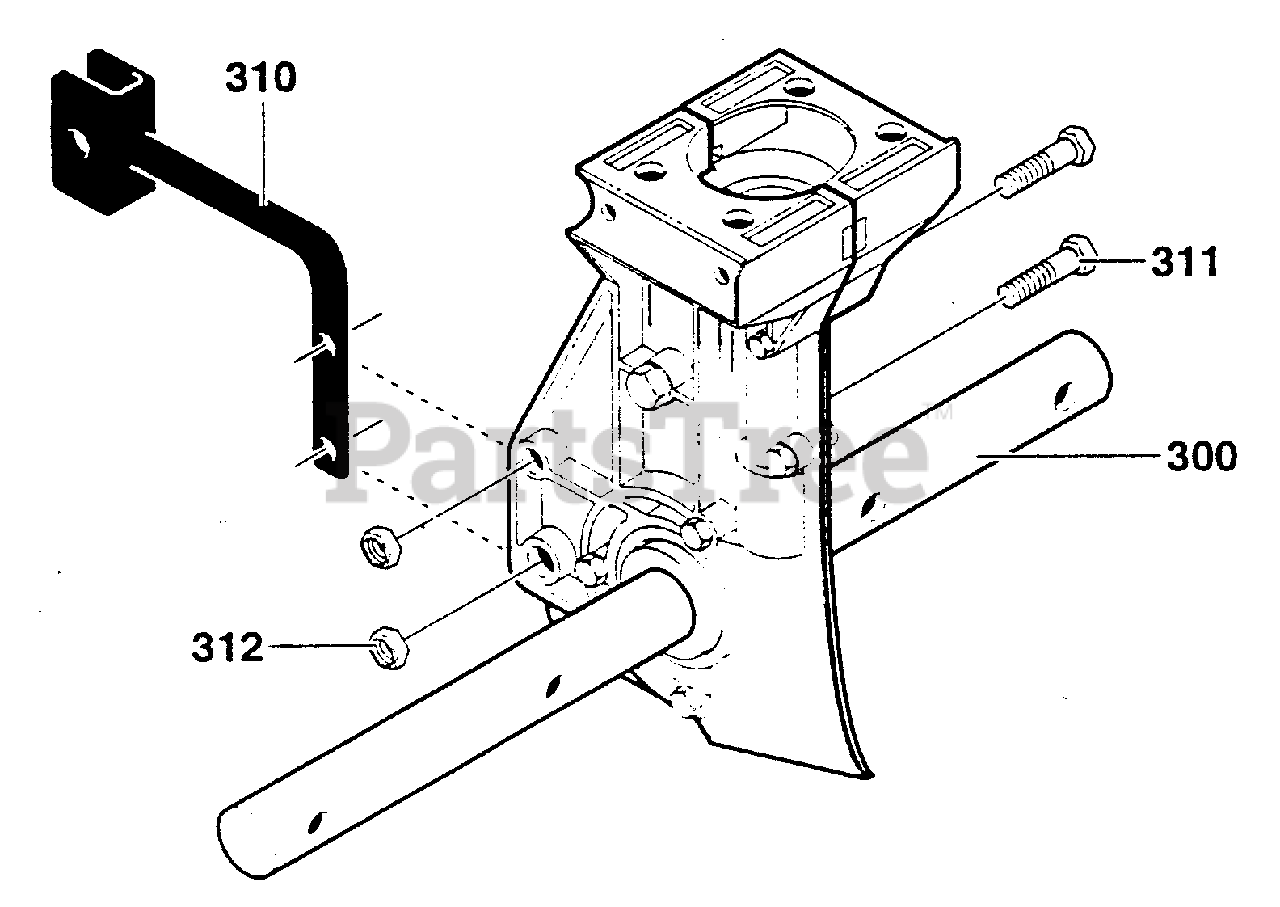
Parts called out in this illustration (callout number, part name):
300	TRANSMISSION ASSY.
310	BRKT,DEPTH FLAT/WIDE
311	SCREW, 1/4-20 X 1.25 HHC
312	NUT, 1/4-20 REGHEXCTRLK
